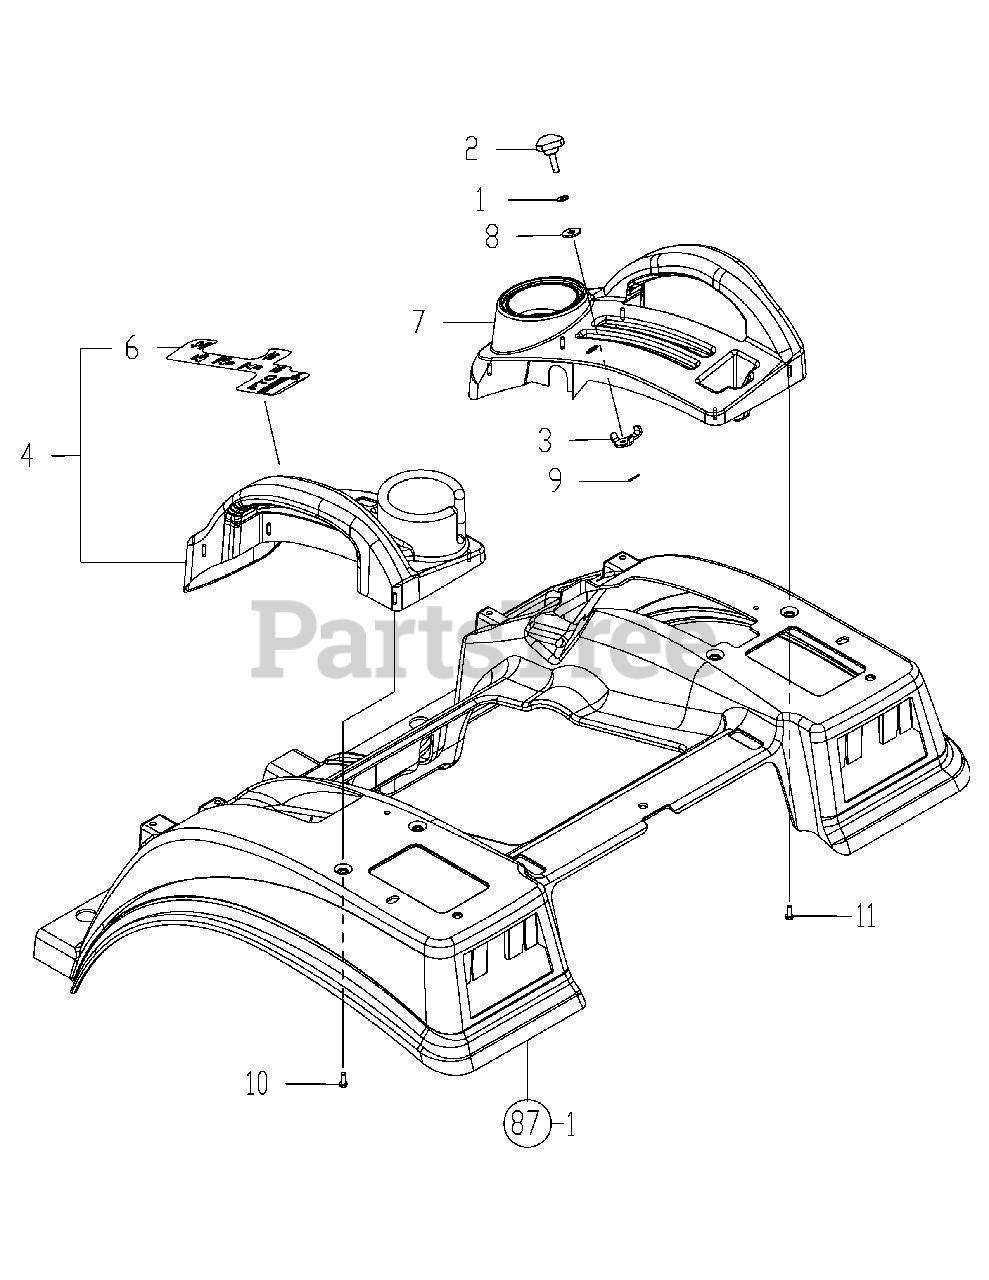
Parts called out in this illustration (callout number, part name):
2	KNOB, HYD. CONTROL
3	STOPPER, HYD. CONTROL
4	GUIDE M ASY, LEVER L
6	LABEL, LEVERGUIDE L
7	GUIDE, LEVER R
10	SCREW, 6.0 X 16
11	SCREW, 6.0 X 16
